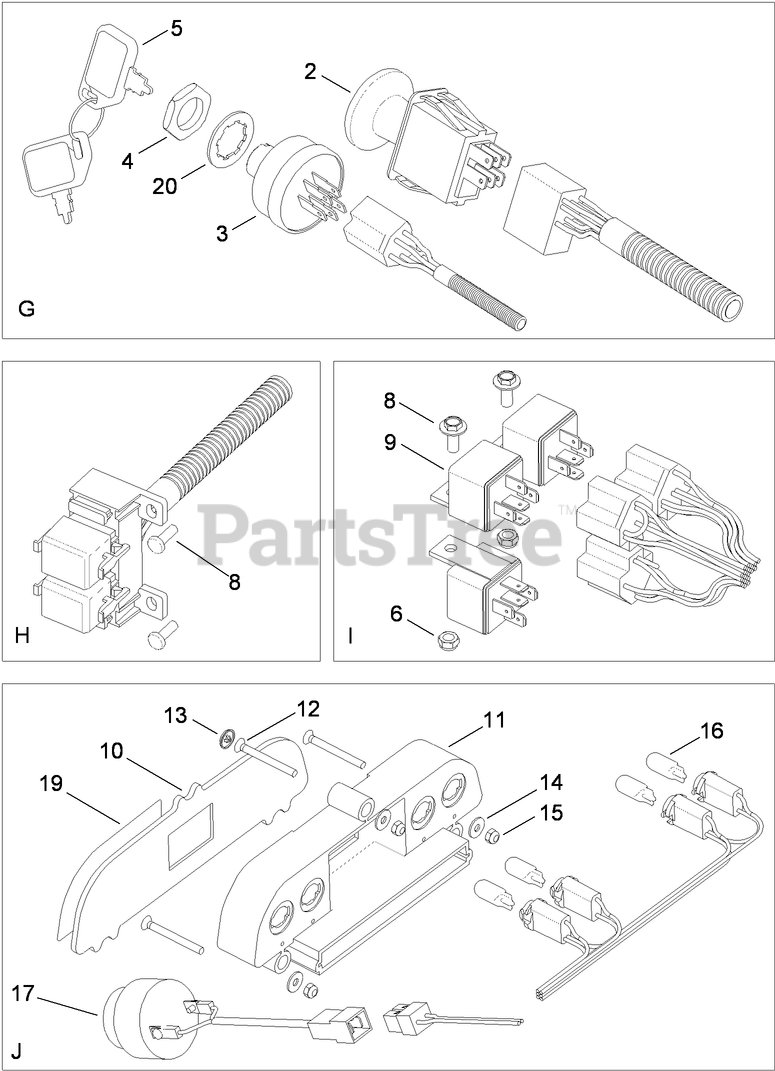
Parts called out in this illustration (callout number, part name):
2	SWITCH-PTO,ON-ON-NONE
3	SWITCH-IGNITION
4	NUT-HH
5	KEY-IGNITION
6	NUT-LOCK
8	SCREW-HEX
10	LENS-DASH LIGHTS
11	HOUSING-LIGHT, INDICATOR
13	CAP-SCREW
14	WASHER
15	NUT-HEX
17	BUZZER
19	DECAL-DASH
20	WASHER-LOCK
